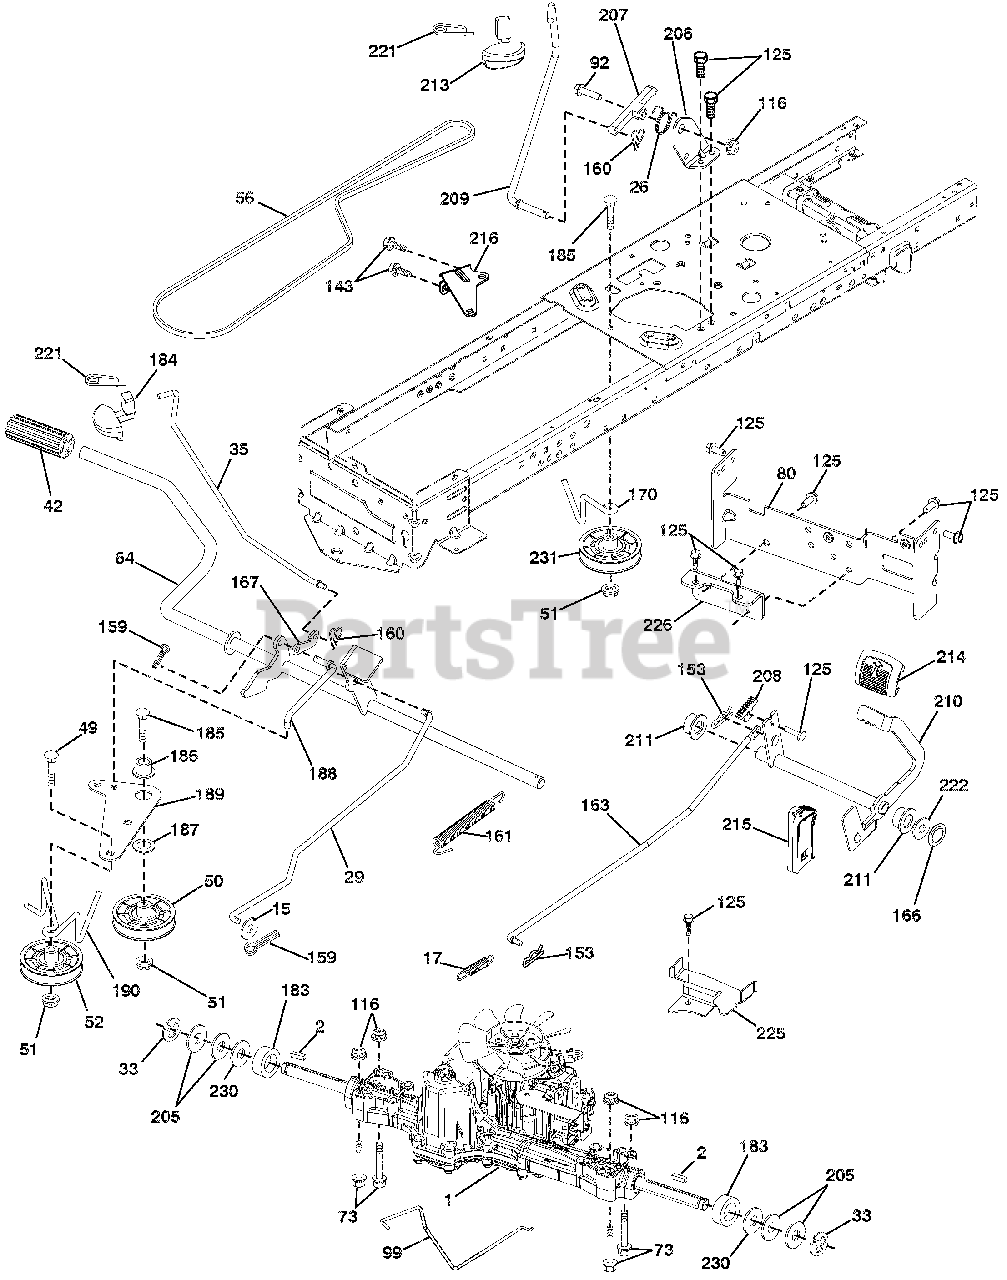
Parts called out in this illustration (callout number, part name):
2	KEY.SQUARE.2.0 X .1845/.1865
15	WASHER.13/32 X 13/16 X 16 GA.
17	SPRING.BRAKE.K46.GREEN
26	SPRING.RETURN.CRUISE
29	ROD.BRAKE.K46
33	E-RING.#5133-75
35	ROD.BRAKE.PARKING.LT.TEX
42	COVER.PEDAL.BLK.ROUND
49	BOLT.RDHD.3/8-16UNCX1-3/4.GR5
50	IDLER.FLAT.910"OFFSET
51	Nut, Hex, Flangelock 3/8-16
52	IDLER.V-GROOVE.910"OFFSET
56	V-BELT.MOWER.92.40.42/K46
64	SHAFT ASM.PEDAL.BRK.CNTRL.PCH
73	BOLT.HEX.FLGHD.5/16-18.GR.5
80	STRAP.TORQUE.K46/18"TEX
92	Bolt, Hex Head 5/16-18 x 1-1/4
99	ROD.SPRING.BYPASS.K46.LT.Z
116	Nut, Lock Hex Flange 5/16-18 u
125	SCREW.5/16-18X3/4.SMGML.TAP/BL
143	SCREW.THDROL.5/16-18 X 1/2TYTT
153	Retainer Spring
159	PIN.COTTER.1/8 X 3/4.CAD.
160	RETAINER.CLIP(M).DIA.290
161	SPRING.RETURN.CLUTCH.6.75
163	ROD.CONTROL.PEDAL.K46
166	NUT.PUSH..625.2006
167	LATCH.BRAKE.PARKING
170	KEEPER.CENTER SPAN.1.688
183	SPACER.AXLE.HYDRO/PEERLES
184	HANDLE.PARKING BRAKE.LTTEX.505
185	BOLT.RDHD.3/8-16UNC X2-3/4 GR5
186	SPACER.RETAINER
187	WASHER.13/32 X 2 X 10 GA.
188	LINK.CLUTCH.GROUND DRIVE
189	BELLCRANK.GROUNDRIVE.NSTG/NSTL
190	KEEPER.BELLCRANK.DRIVE.GROUND
205	WASHER.25/32 X 1-5/8 X 16GA.
206	BRACKET.MOUNT.LATCH.CRUISE
207	LATCH.CONTROL.CRUISE
208	GEAR SECTOR.CONTROL.CRUISE
209	ROD.CONTROL.CRUISE.LT.ELITE
210	ROCKER ASM.PEDAL CONTROL.TEXLT
211	BEARING.NYLON.BLK..629 ID.
213	HANDLE.CONTROL.CRUISE.ELTE.428
214	PAD PEDAL FORWARD
215	PEDAL.REVERSE.TEX.GT.428
216	BRACKET.PULLEY.IDLER.WTEX
221	RETAINER.SPRING.CLIP.HANDLE
222	WASHER.21/32X1-1/4.10GA.N/PLTD
225	KEEPER.BELT.TRANSAXLE.K46
226	BRACKET.MOUNT.TORQUE.K46.TLT
230	WASHER.HARDEN..793 X 1.637X060
231	IDLER.V-GROOVE.1.688"OFFSET
